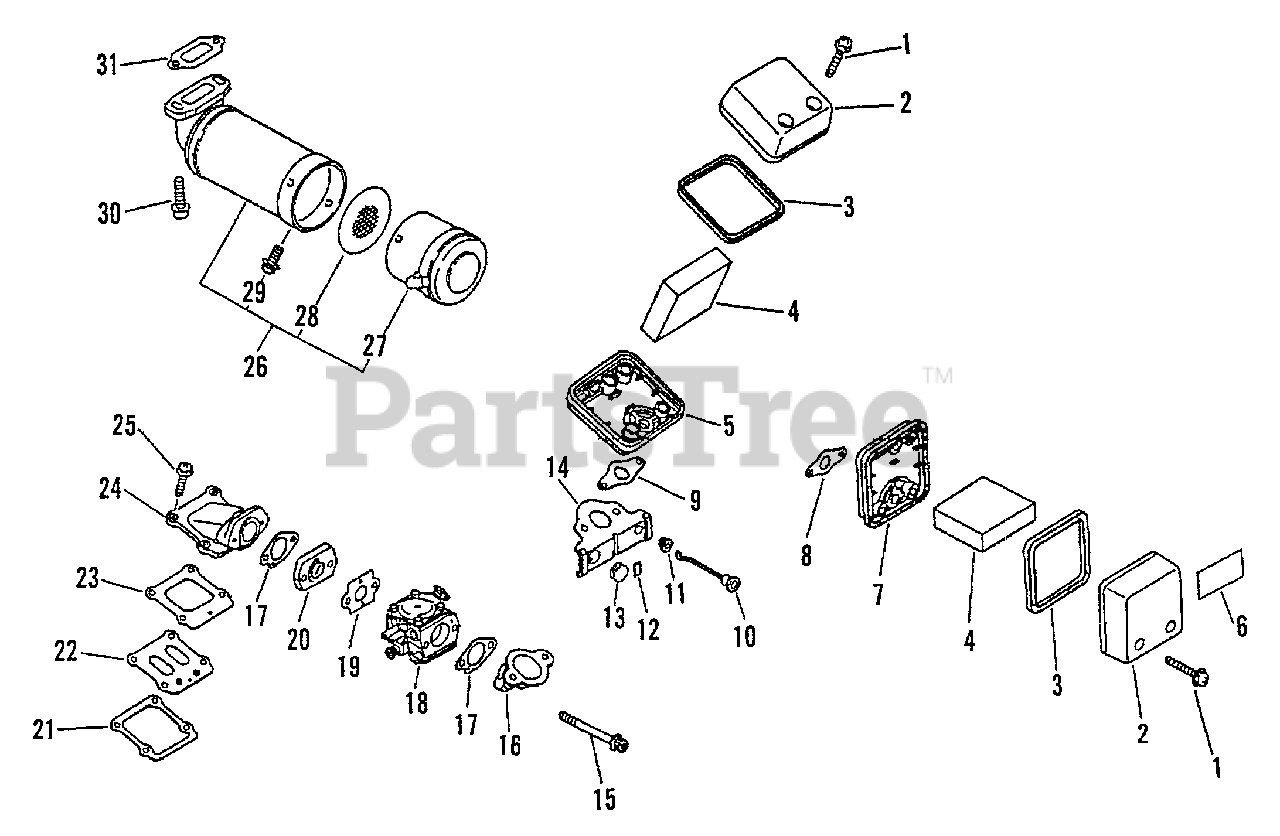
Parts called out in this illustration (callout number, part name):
1	SCREW - 5X40
2	COVER, AIR FILTER
3	SEAL, CLEANER
4	FILTER, AIR
5	CASE, AIR FILTER
6	LABEL - CAUTION
7	CASE, AIR FILTER
8	GASKET, INTAKE
9	GASKET, CLEANER
10	ROD, CHOKE
11	GROMMET
12	LABEL - CHOKE
14	BRACKET, SWITCH
15	SCREW - 5X60
16	ADAPTOR, INTAKE
17	GASKET, INTAKE
18	CARBURETOR WT-233
19	GASKET, INTAKE
20	INSULATOR, INTAKE
21	GASKET, REED VALVE
22	REED VALVE ASSY
23	GASKET, REED VALVE
24	ADAPTOR, INTAKE
25	SCREW - 5X18
26	MUFFLER ASSY
27	LID, MUFFLER
28	SCREEN, SPARK ARRESTOR
29	SCREW - 5X10
30	SCREW - 5X14
31	GASKET, EXHAUST
